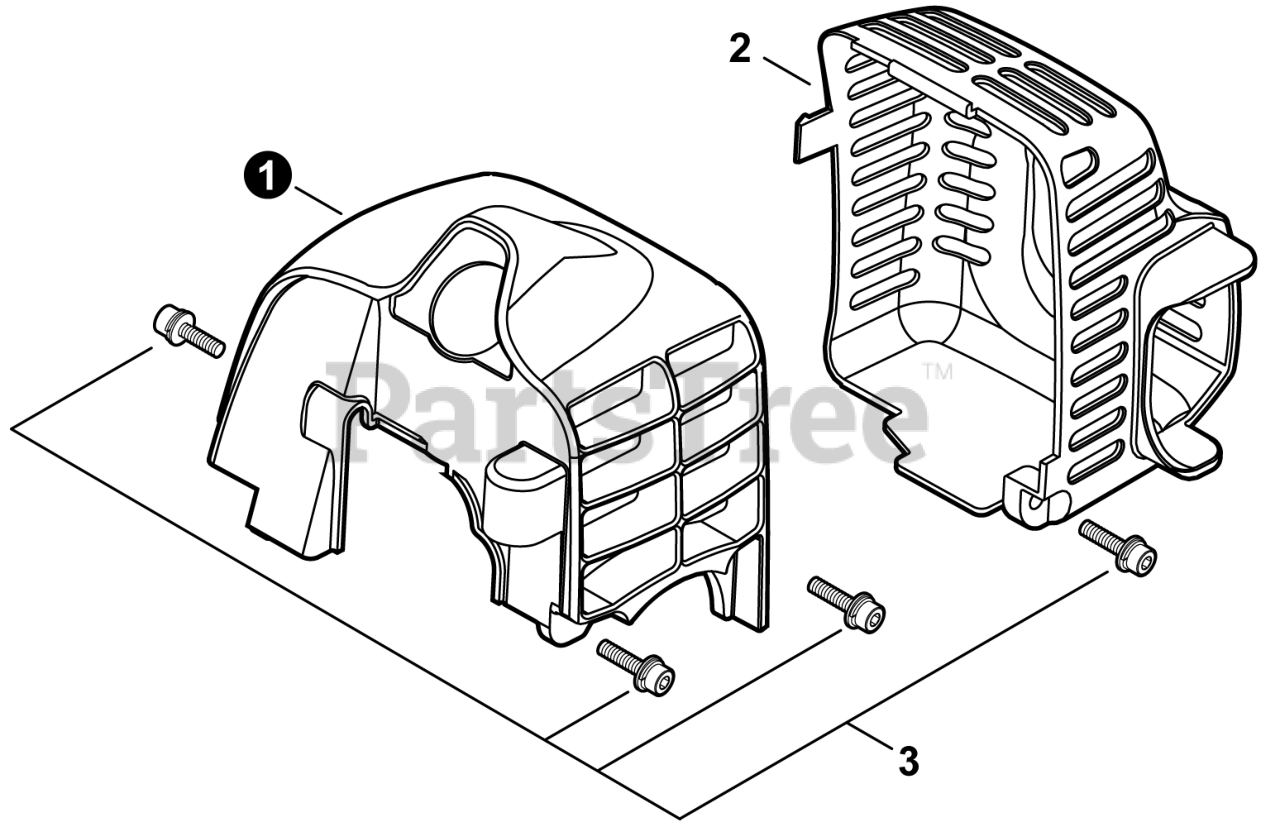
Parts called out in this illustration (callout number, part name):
1	COVER, ENGINE
2	COVER, MUFFLER
3	BOLT M4×16
